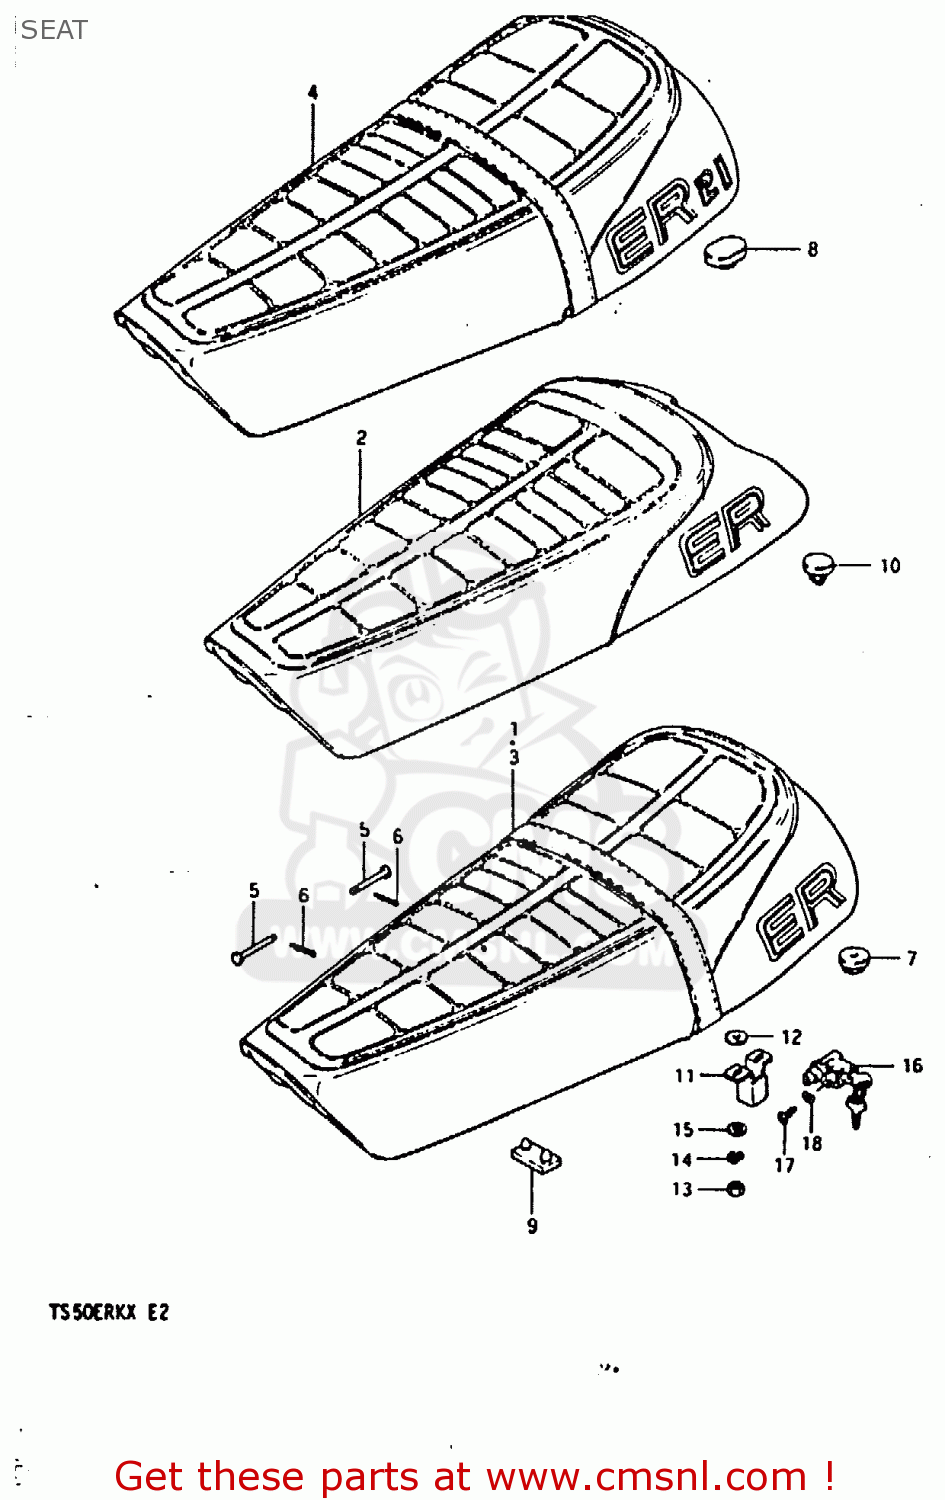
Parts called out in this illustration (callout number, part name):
1	SEAT ASSY (BLACK)
5	PIN
6	PIN
7	CUSHION
9	CUSHION
11	PLATE,CLAMP GUIDE
12	WASHER(8.5X18X1)
13	NUT
14	LOCK WASHER
15	WASHER
16	LOCK ASSY,SEAT
17	SCREW
18	LOCK WASHER
